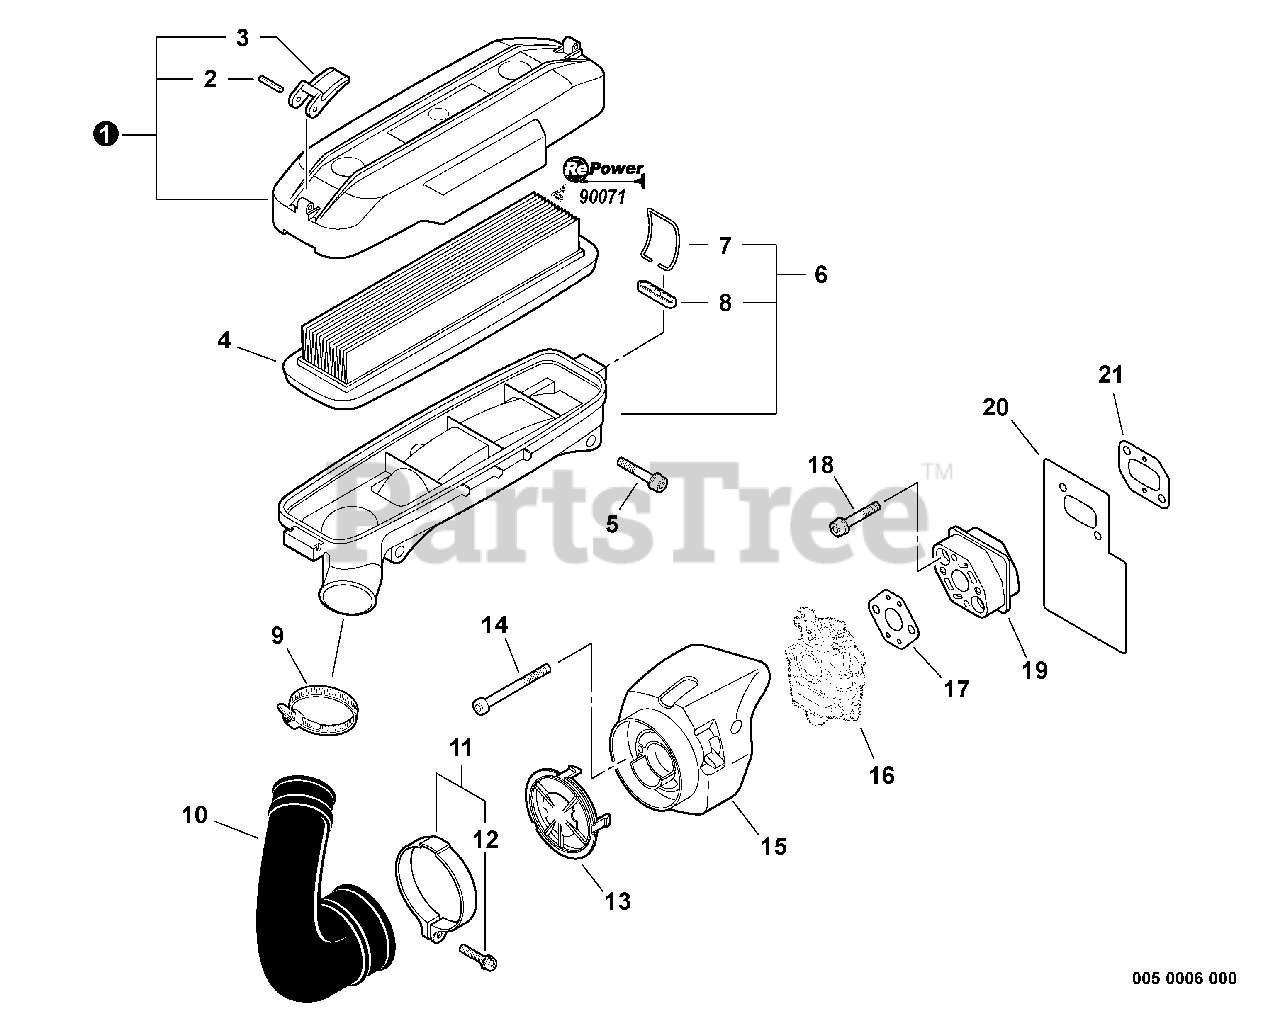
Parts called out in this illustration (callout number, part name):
1	COVER, AIR FILTER
2	PIN, SPRING 3×25
4	FILTER, AIR
5	SCREW 5×35
6	CASE ASSY, AIR FILTER
9	CLAMP 33 MM /57 MM
10	PIPE, INTAKE
11	CLAMP KIT
12	SCREW 5×25
13	PLATE, PREVENT
14	BOLT 5×55
15	CASE ASSY, AIR FILTER
16	CARBURETOR
17	GASKET, INTAKE
18	BOLT 5×25
19	INSULATOR, INTAKE
20	HEAT SHIELD, INTAKE
21	GASKET, INTAKE
22	TUNE-UP KIT - REPOWER
